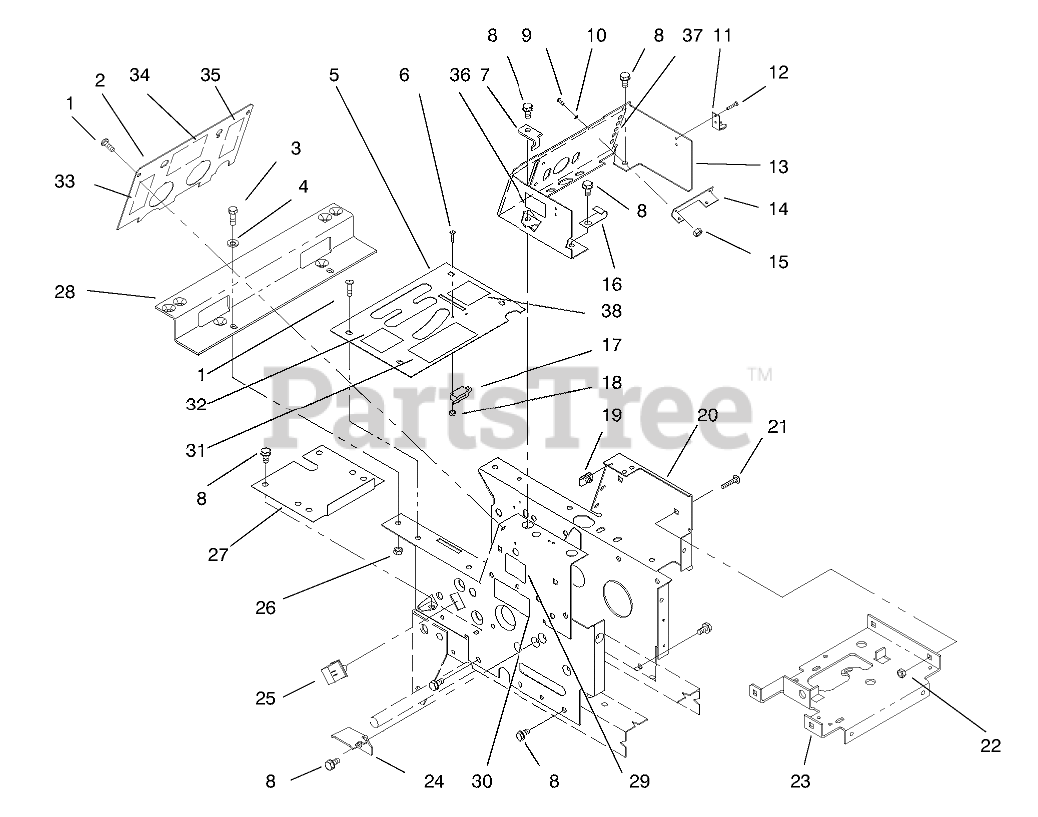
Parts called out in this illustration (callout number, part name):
1	SCREW-PPH
2	PLATE HOODSTAND (BLACK)
3	SCREW-HH
4	WASHER-PLAIN
5	Plate-Shift
6	SCREW-PPH
7	STOP-PTO
8	Bolt
9	SCREW-PAN
10	Washer-Lock
11	KEEPER-LATCH
12	RIVET-POP
13	CONSOLE (BLACK)
14	BRACKET
15	Nut
16	J-CLIP
17	SWITCH
18	NUT-HEX
20	Hoodstand
21	BOLT CARR. 5/16X1/2 BK
22	Nut
23	SUPPORT-BATTERY
24	BRACKET-BELT SUPPORT
25	SWITCH INTERLOCK
26	NUT-LOCK, NI
27	COVER-DUST
28	Bracket-Fender
29	DECAL-EUROPE
30	DECAL - MODEL 416-8
31	DECAL-DANGER
31	DECAL - DANGER
32	DECAL - SHIFT PATTERN
33	DECAL - PTO CLUTCH
34	Decal-Plate
35	DECAL - LIFT
36	DECAL - ELEC SYSTEM
37	DECAL - LOWER DASH
38	DECAL - PARKING BRAKE
